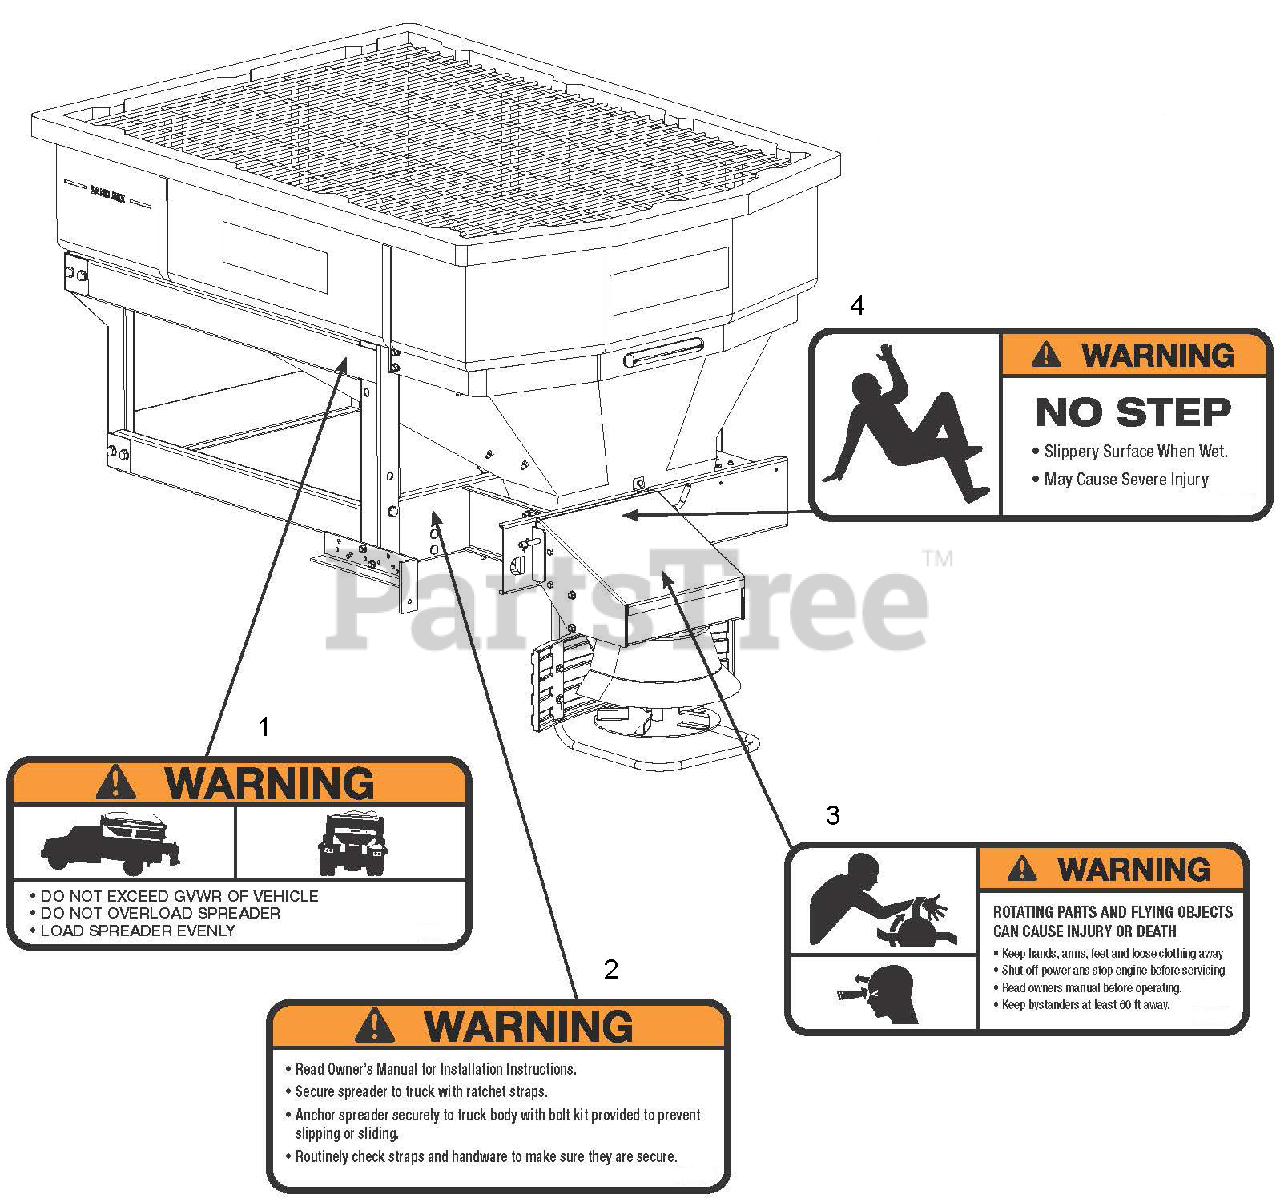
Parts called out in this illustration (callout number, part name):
1	DECALWARNING - GVWR
2	DECALWARNING - READ OWNER'S MANUAL
3	WARNING DECAL ROTATING PARTS
4	DECALWARNING - NO STEP
